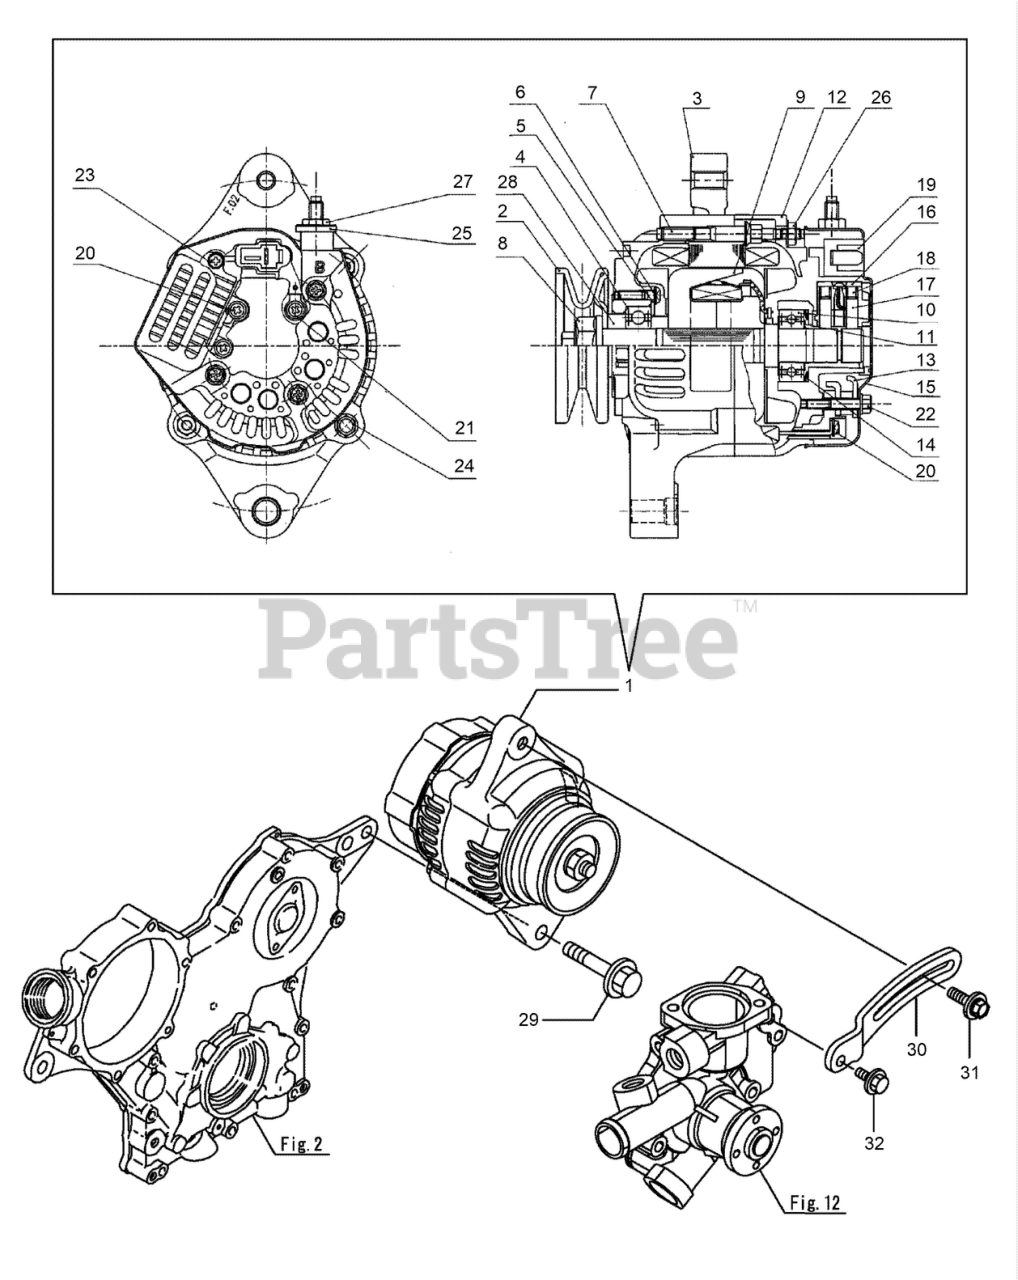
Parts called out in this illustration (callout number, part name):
1	ALTERNATOR, 12V-40A
2	PULLEY, GENERATOR
3	FRAME ASSY, DRIVE
4	BEARING, BALL
5	PLATE, RETAINER
9	ROTOR ASSY
10	BEARING, BALL
11	COVER, BEARING
12	FRAME, END RR
13	HOLDER ASSY, RECTIFI
14	WASHER
15	COVER, END RR
16	HOLDER ASSY, BRUSH
17	BRUSH ASSY, SUB
18	SPRING, COIL
19	REGULATOR ASSY
23	SCREW, W/WASHER
25	BUSH, INSULATION
28	COLLAR
30	ADJUSTER, BELT
31	BOLT-ADJUSTING
